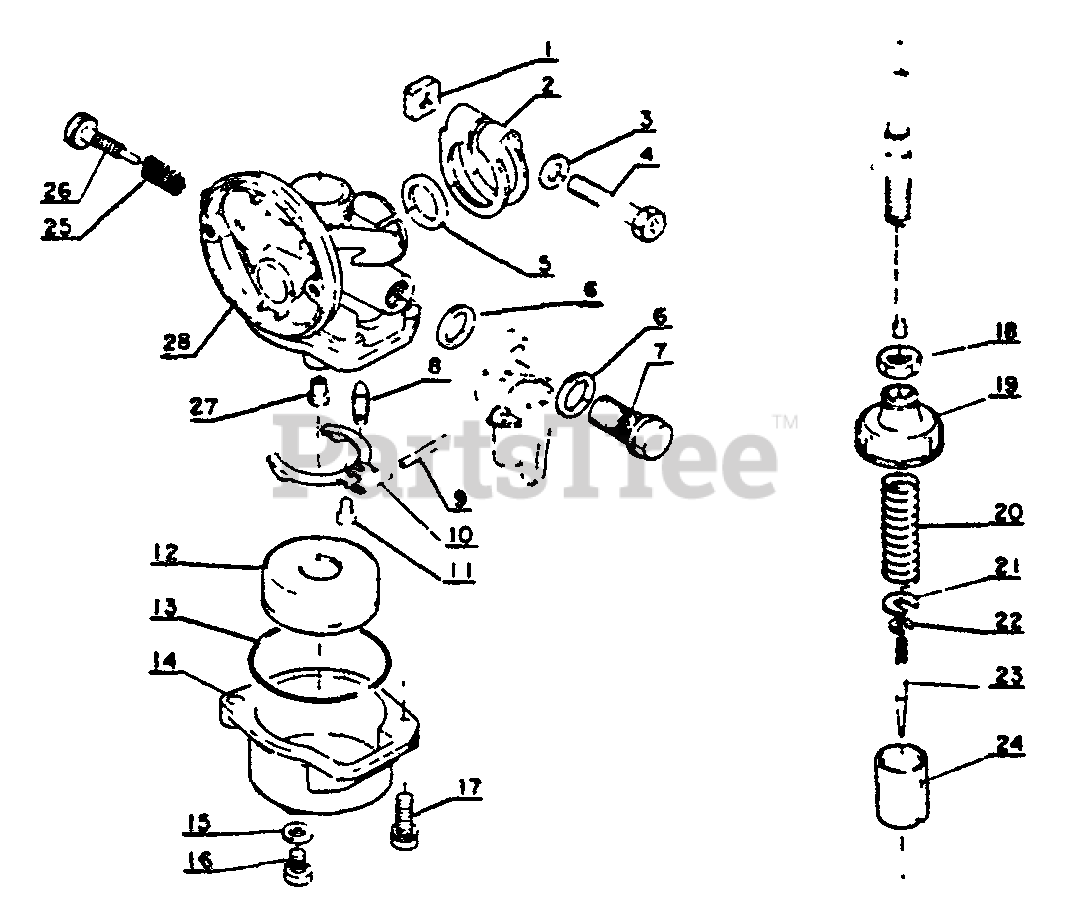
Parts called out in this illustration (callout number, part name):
1	NUT
2	CLIP
3	WASHER, FLAT 5.5×10×0.8
4	BOLT
6	GASKET
7	BOLT, BANJO
8	VALVE, INLET NEEDLE
9	PIN, METERING LEVER
10	LEVER, METERING
11	SCREW 4×6
12	FLOAT
13	GASKET, CHAMBER
14	CHAMBER, FLOAT
16	SCREW 4×6
17	SCREW 4×12
18	NUT
19	COVER, TOP
20	SPRING, THROTTLE
21	SEAT, SPRING
22	E-RING
23	NEEDLE, JET
24	VALVE, THROTTLE
25	SPRING, IDLE ADJUST
26	SCREW, IDLE ADJUST
27	JET, MAIN
28	BODY, CARBURETOR
